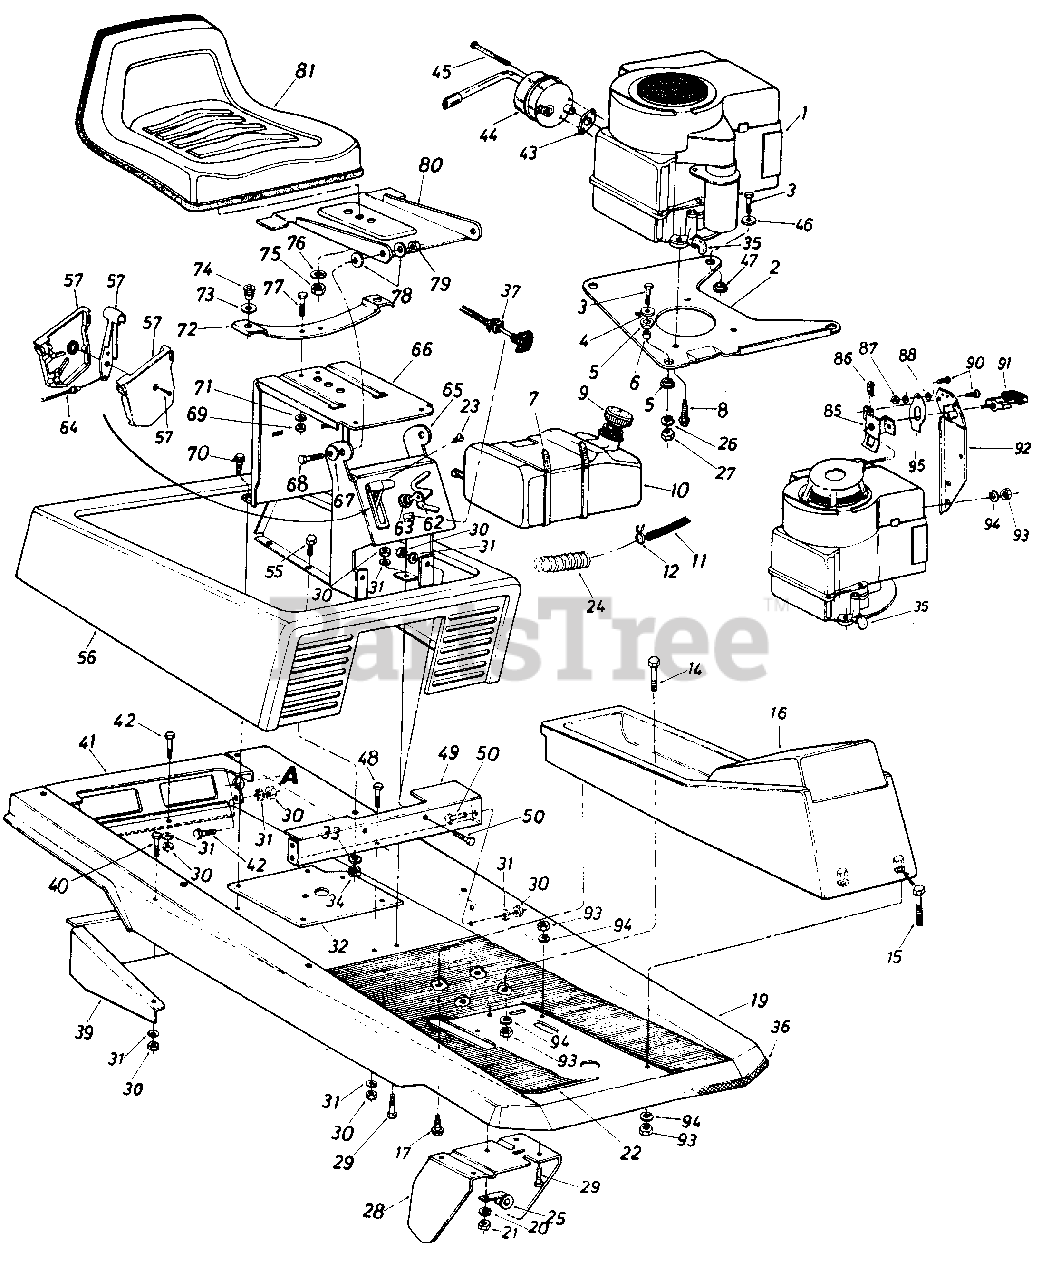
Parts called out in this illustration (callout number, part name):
1	Engine
2	Engine Mounting Plate
3	Hex Bolt 5/16-24 x 1.25" Lg.
4	Fl-Wash. .330" I.D. x 1.125" O.D.
5	Engine Mounting Grommet
6	Spacer .315" I.D. x .50" O.D. x .520" Lg.
7	Cable Tie 30.6 Lg.
8	Hex Wash. Hd. Self-Tap Scr. 3/8-16 x 1.25" Lg.
9	Gas Gauge
10	Fuel Tank
11	Gas Line
12	Hose Clamp-.406" Dia.
14	Hex Bolt 5/16-18 x 1.75" Lg.*
15	Hex Bolt 5/16-18 x 2.0" Lg.*
16	Front Console
17	Plastite Scr. 5/8 x 1.25"
19	Main Frame
20	L-Wash. 5/16" I.D.*
21	Hex Nut 5/16-18 Thd.*
22	Floor Mat
23	Truss Mach. AB-Tap Scr. #10 x .50" Lg.
24	Convoluted Conduit
26	L-Wash. 5/16" I.D.*
27	Hex Nut 5/16-24 Thd.*
28	Clutch-Brake Pedal Ass'y.
29	Hex Bolt 5/16-18 x .75" Lg*
30	Hex Nut 5/16-18 Thd.*
31	L-Wash. 5/16" I.D.*
32	Mounting Brkt. Variable Speed Pulley
33	L-Wash. 1/4" I.D.*
34	Hex Nut 1/4-20 Thd.*
35	90ø Elbow Male To Female
36	Trim Strip 18" Lg.
37	Choke Control
39	Transaxle Support Ass'y.
40	Hex Bolt 5/16-18 x .75" Lg.*
43	Exhaust Gasket (8 H.P.)
44	Muffler Ass'y. (8 H.P.)
45	Shld. Bolt (8 H.P.)
46	Fl-Wash. .330" I.D. x 1.25" O.D.
47	Flange Wash. .320" I.D. x .750" O.D.
49	Seat Support & Frame Brkt.
50	Hex Bolt 5/16-18 x .75" Lg.*
55	Hex Bolt 1/4-20 x .50" Lg.**
56	Engine Cover Ass'y.
57	Throttle Control Box Ass'y.
62	Ignition Key
63	Ignition Switch
64	Throttle Control Wire
65	Front Seat Bracket
66	Rear Seat Bracket
67	Bell-Wash. .345" I.D. x .88" O.D.
68	Hex Bolt 5/16-18 x .75" Lg.
69	Hex Nut 5/16-18 Thd.
70	Hex Self-Tap Scr. 5/16-18 x .75" Lg.
71	L-Wash. 1/4" I.D.
72	Seat Spring
73	Fl-Wash. .531" I.D. x .930" O.D.
75	Hex Wash. Hd. Tap Scr. 3/8-16 x 3/4" Lg.
76	L-Wash. 1/2" I.D.*
77	Hex Bolt 1/4-20 x .75" Lg.
78	Bell-Wash. .345" I.D. x .88" O.D.
79	Hex Cent. L-Nut 5/16-18 Thd.
80	Seat Pivot Bracket
81	Seat Ass'y. Comp.
93	Hex Nut 5/16-18 Thd.*
94	L-Wash. 5/16" I.D.*
15571-0629	PANEL-FRAM - SILVER FLAKE (0629)
15571-0638	PANEL-FRAM - MTD/TROY-BILT RED (0638)
